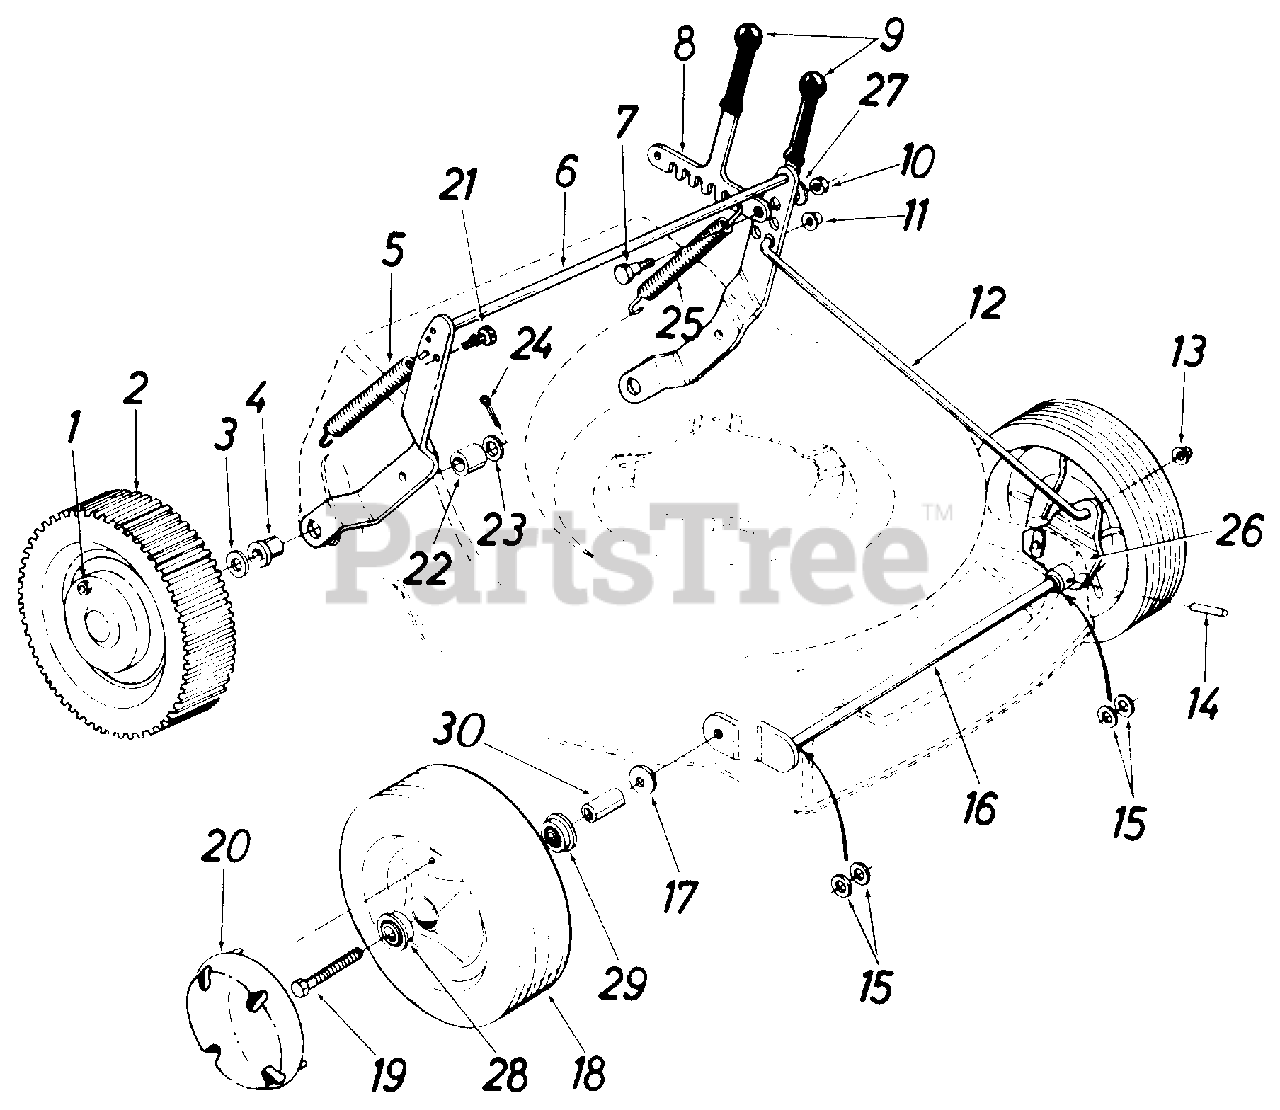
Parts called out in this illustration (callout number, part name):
1	Hex Ins. L-Nut 1/4-20 Thd.
2	Rear Wheel Ass'y.
3	Fl-Wash. .510 I.D. x .930 O.D.
4	Flange Brg. .506 I.D.
5	Extension Spring .50 O.D. x 4.25
6	Rear Wheel Pivot Brkt. Ass'y.
7	Shld. Bolt. .437 Dia. x .180
8	Height Adjusting Lever
9	Grip Black
10	Hex Nut 5/16-18 Thd.
11	Push Cap 5/16" Rod
12	Linkage Rod .31 O.D. x 23.25" Lg.
13	Push Cap 5/16" Rod
14	Spring Pin Roll 3/16" Dia. x 1.00" Lg.
15	Fl-Wash. .510 I.D. x 1.00 O.D.
16	Wheel Axle Brkt. Ass'y.
17	Bell-Wash. .400 I.D. x .88 O.D. x .060
18	Front Wheel Ass'y. Comp.
19	Hex Scr. 3/8-16 x 2.00" Lg.
21	Rubber Bumper
22	Spacer .70 I.D. x .88 O.D. x 1.00" Lg
23	Fl-Wash. .510 I.D. x .930 O.D. x .050
24	Cotter Pin 3/32" Dia. x 1.00" Lg.
25	Extension Spring .50 O.D. x 4.25
26	Front Wheel Brkt. Ass'y.
27	L-Wash. 5/16" Scr.
28	Ball Bearing 3/8" I.D.
29	Ball Bearing 1/2" I.D.
30	Spacer 3/8" I.D.
